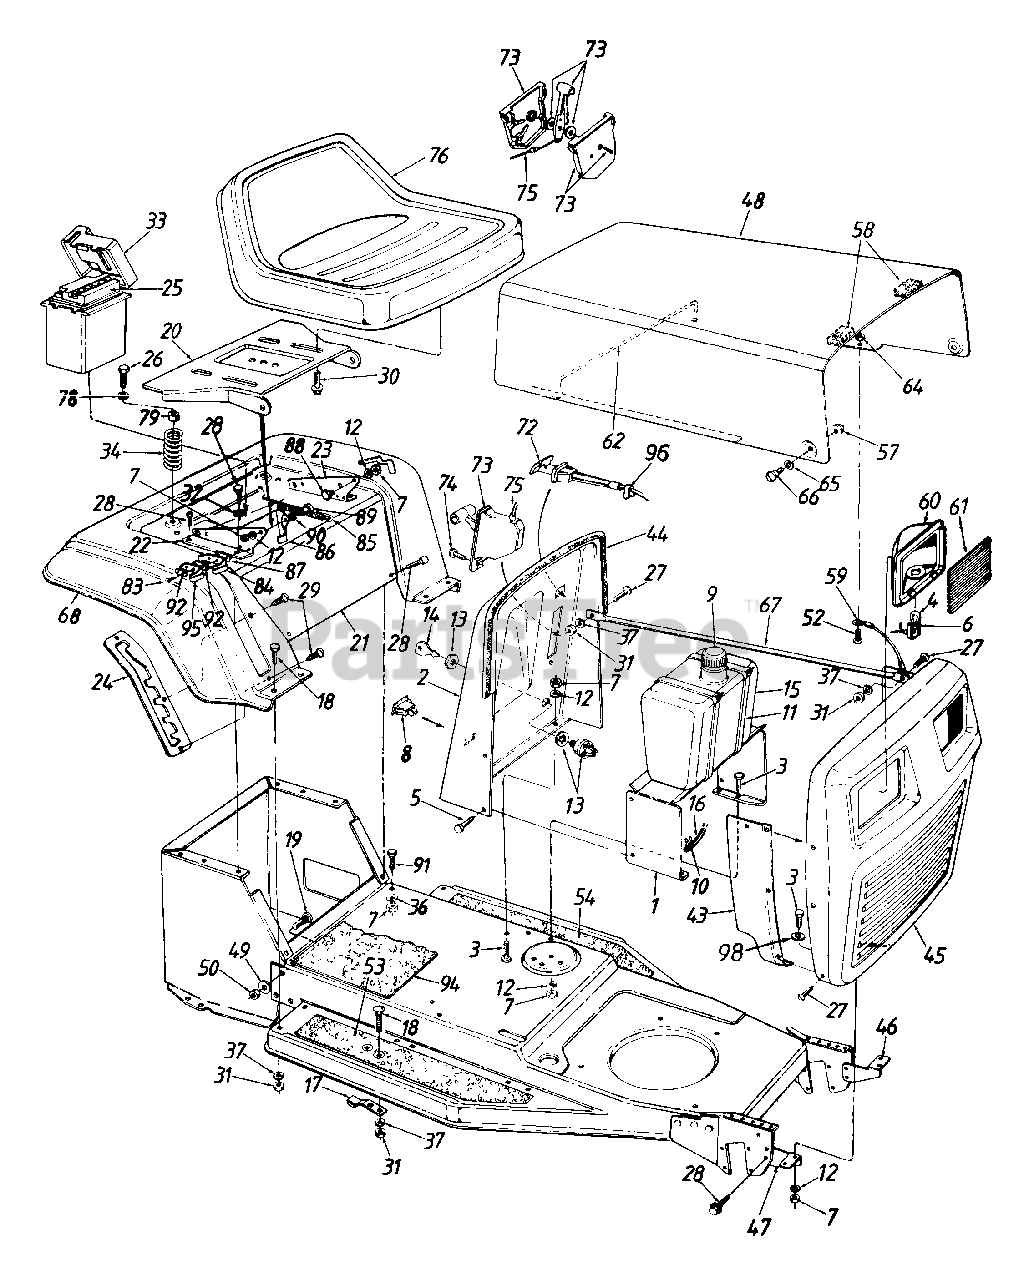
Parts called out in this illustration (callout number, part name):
1	Dash Panel Support Brkt.
4	Bulb
5	Hex AB-Tap Scr. 1/4 x .62"
6	Socket
7	Hex Nut 5/16-18 Thd.
8	Light Switch
9	Gas Cap
10	Hose Clamp
11	Cable Tie
12	L-Wash. 5/16" I.D.
13	Ignition Switch
14	Ignition Key
15	Fuel Tank
16	Gas Line 15" Long
17	Blade Brake Ass'y.
18	Carriage Bolt 1/4-20 x .62"
19	Ribbed Neck Bolt 3/8-24 x .8"
20	Seat Pivot Brkt.
25	Battery
26	Hex Self-Tap Scr. 5/16-18 x 1.25" Lg.
27	Truss Mach. Scr. 1/4-20 x .62" Lg.
28	Hex AB-Tap Scr. 5/16 x .75" Lg.
29	Torx Mach. AB-Tap Scr. 1/4 x .62" Lg.
30	Hex Self-Tap Scr. 3/8-16 x .75" Lg.
31	Hex Nut 1/4-20 Thd.
32	External L-Wash. 5/16" I.D.
33	Battery Box w/Cover
34	Compression Spring
36	Bell-Wash. 5/16" I.D.
37	L-Wash. 1/4" L.D.
47	Grille Mtg. Brkt. - R.H.
50	Hex L-Nut 3/8-24 Thd.
52	Truss Mach. Scr #10-24 x .5" Lg.
53	Foot Pad - R.H.
54	Foot Pad - L.H.
57	Lock Nut 1/4-28 Thd.
58	Foam Strip
59	Hood Stop
60	Headlight Housing
61	Lens
62	Hood Spring
64	Hex Sems Nut #10-24 Thd.
65	Spr. Wash 39" I.D. x .62" O.D.
66	Shld. Bolt
72	Choke Control
73	Throttle Control Box
74	Truss AB-Tap Scr. #10 x .5"
75	Throttle Wire (B&S)
75	Throttle Wire (Tec.)
76	Seat Assembly (Low Back)
76	Seat Assembly (Medium Back)
76	Seat Assembly (High Back)
76	Seat Assembly (Low Back - Yellow)
78	Fl-Wash. .344" I.D. x .88" O.D.
79	Bushing
83	Hex Tap Scr. #8 x .5" Lg.
84	Safety Switch (Seat)
85	Ext. Spring 5.31" Lg.
86	Seat Lift Brkt.
87	Insulator Boss Plate
88	Shld. Bolt .437" Dia. x .162" Lg.
89	Shld. Bolt .437" Dia. x .268" Lg.
90	Spr. Wash .445" I.D. x .75" O.D.
91	Hex . Wash. Hd. Scr. 5/16-18 x .62" Lg
92	Insulator Plate
94	Center Foot Pad
95	Safety Switch (Seat)
96	Retainer Clip
98	Fl-Wash. .34" I.D. x 1" O.D.
